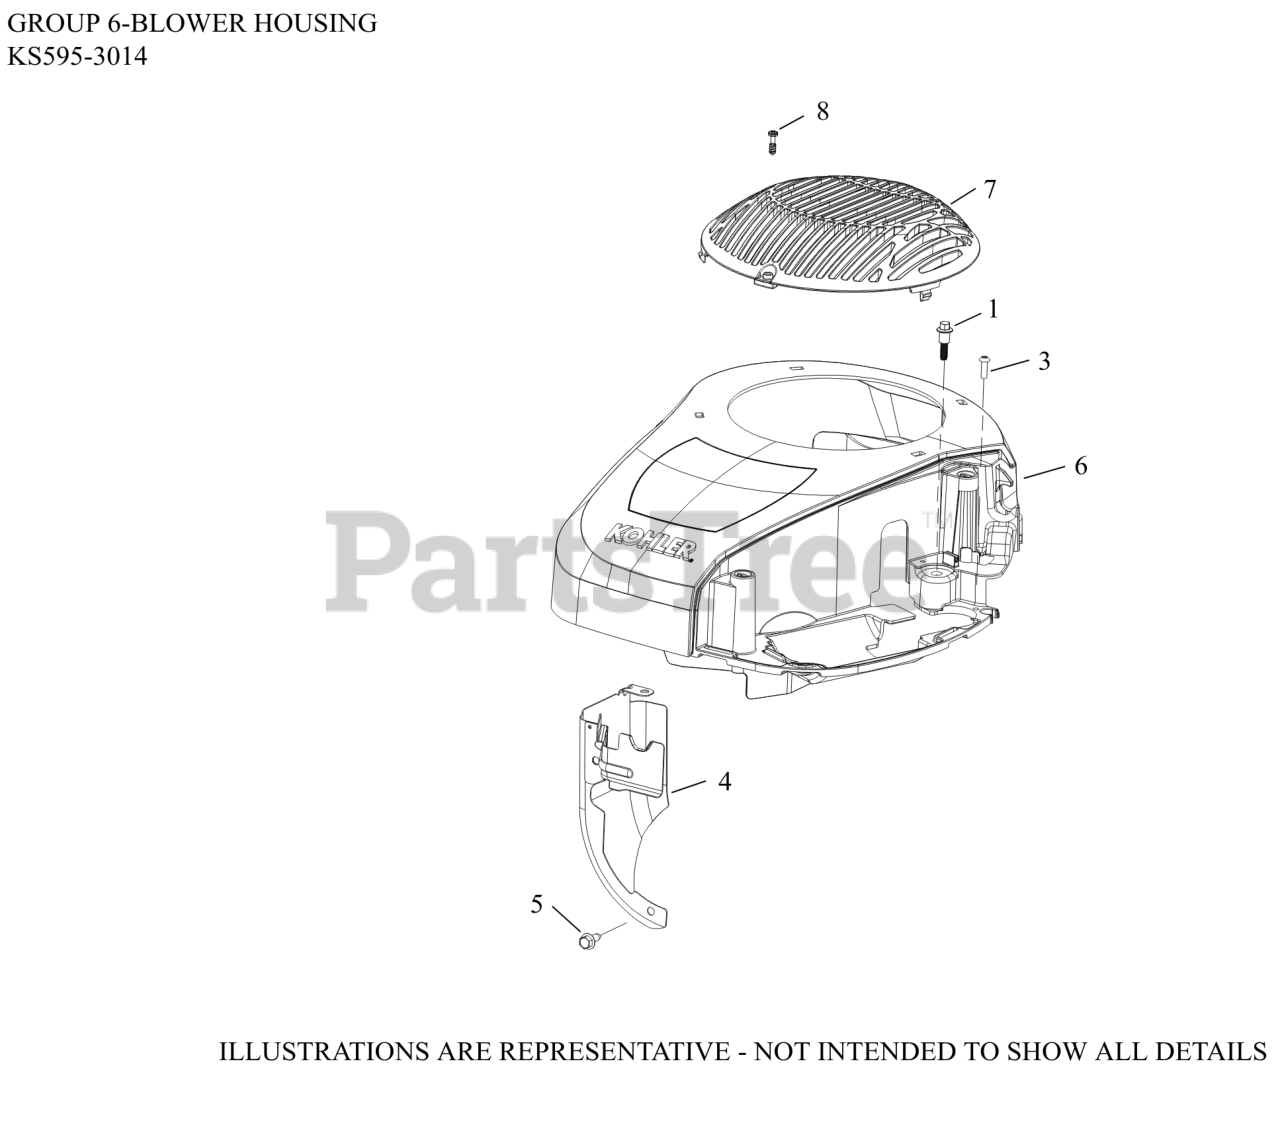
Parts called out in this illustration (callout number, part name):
1	SCREW, SHD THD FRM M6X1X26
3	SCREW, HI-LOW
4	BAFFLE, BARREL ASSY
5	SCREW, THREAD FORMING
6	KIT, BLOWER HOUSING-USE 22 027 05-S
7	GUARD, FIXED
8	SCREW, M5-2.42 (PT) THREAD
